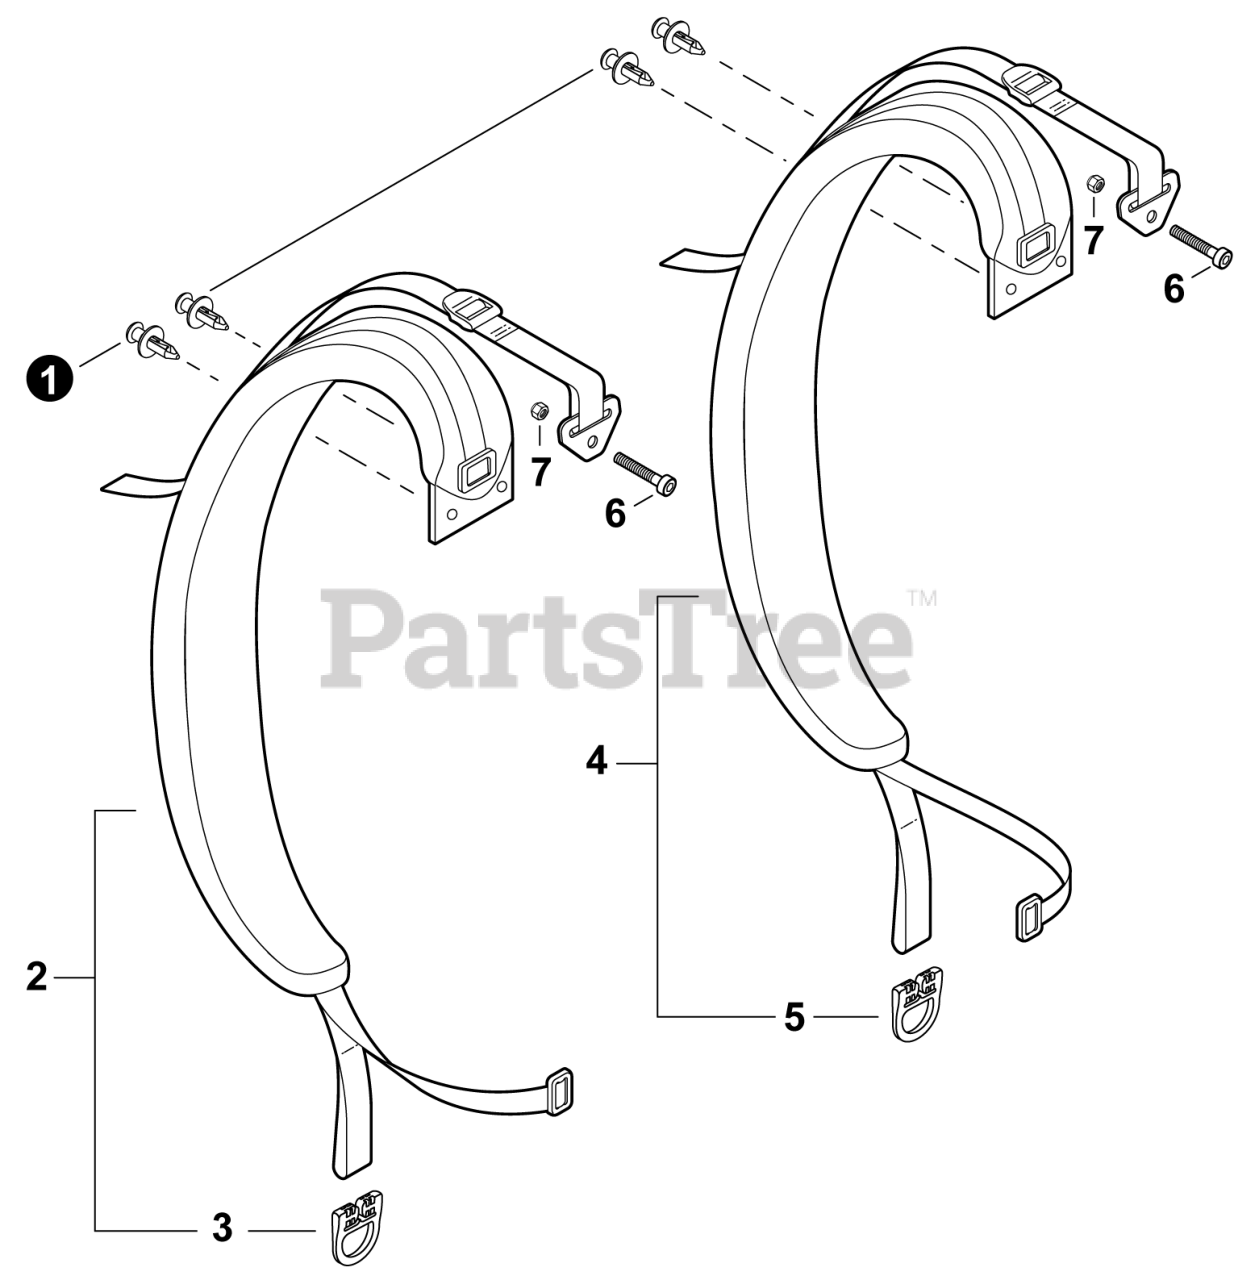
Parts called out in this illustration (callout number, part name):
2	HARNESS ASSY, LEFT
3	BUCKLE, HARNESS
4	HARNESS ASSY, RIGHT
5	BUCKLE, HARNESS
6	BOLT, TORX 5x30
7	NUT, LOCK M5
